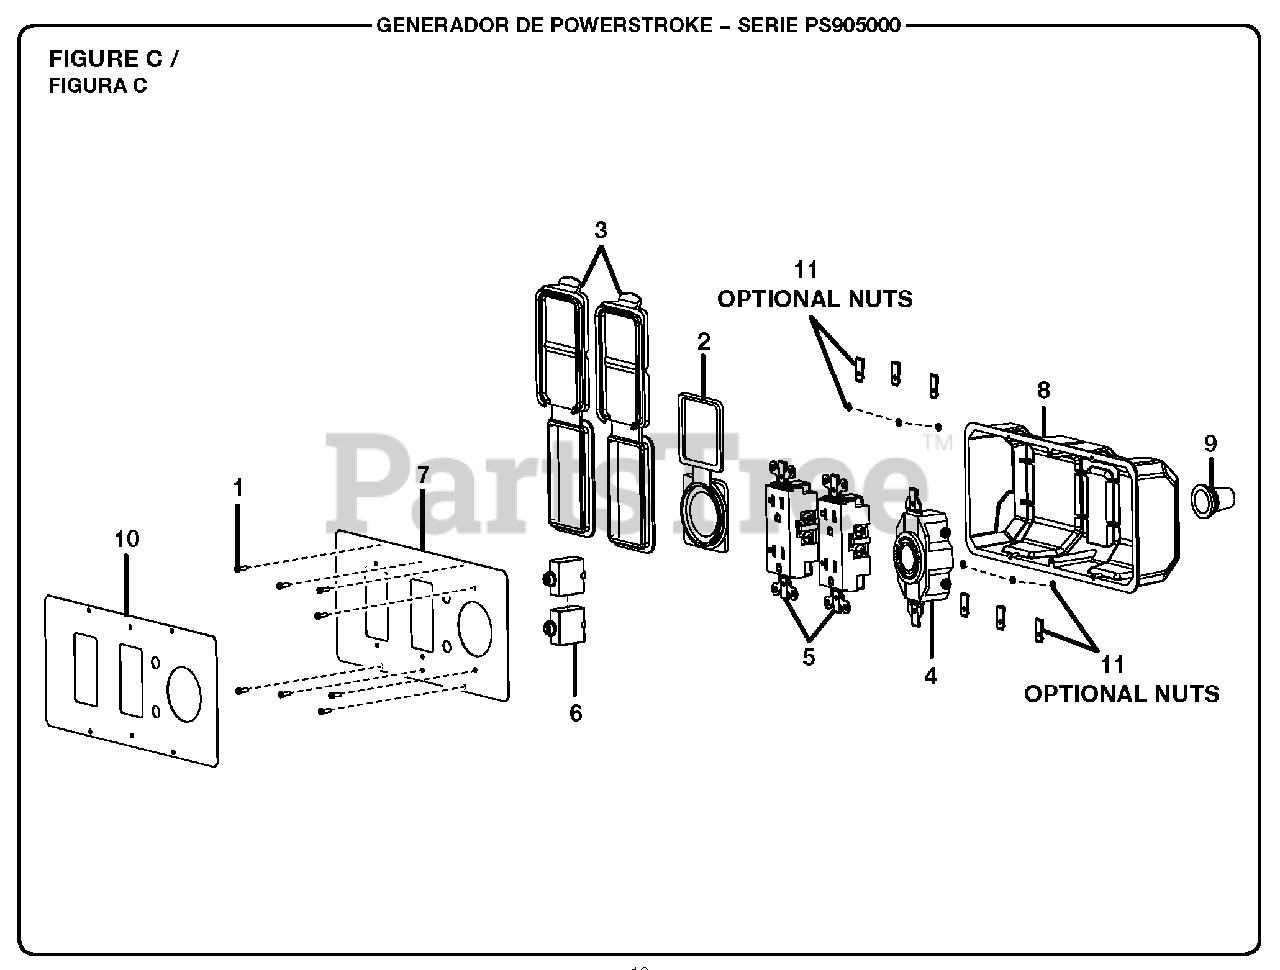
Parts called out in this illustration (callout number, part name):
1	Screw (#6-20 x .38 in.)
2	Outlet Cover (240 Volt)
3	Outlet Cover (120 Volt)
4	Twist Lock Receptacle (240 Volt)
5	Duplex Receptacle (120 Volt)
6	Circuit Breaker (20 Amp)
7	Front Panel
8	Control Box (Back Panel)
9	Rubber Sleeve
10	Front Panel Label
11	Lock Nut (#6- 32)
